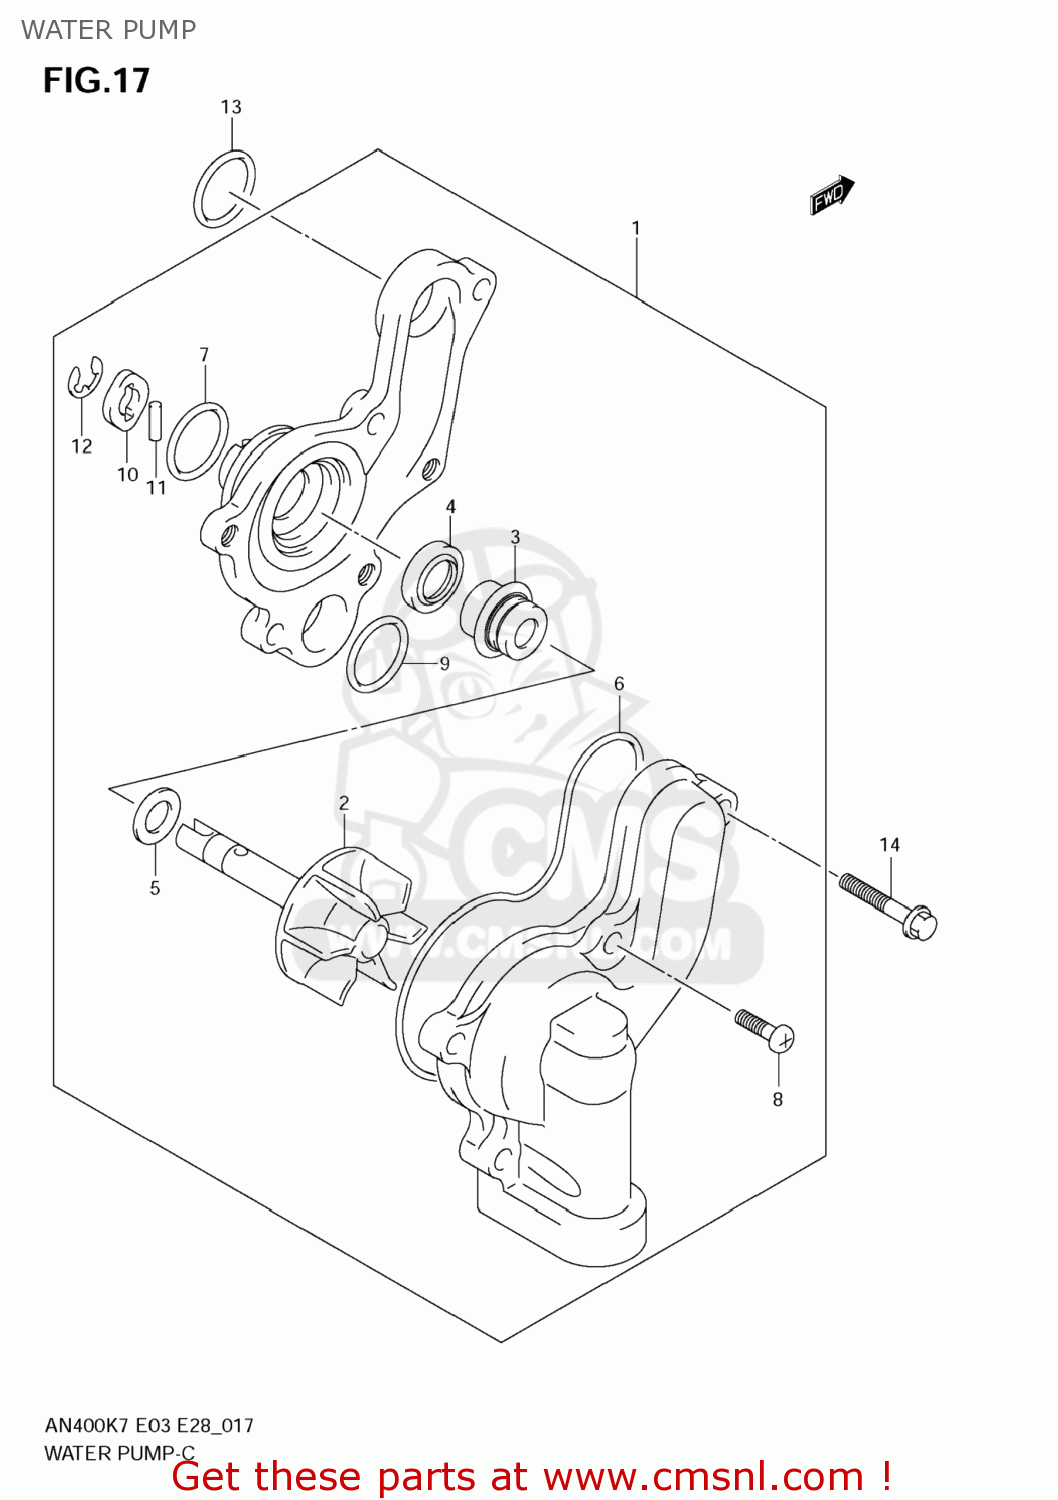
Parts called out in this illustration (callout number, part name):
1	PUMP ASSY,WATER
2	IMPELLER
3	SEAL,MECHANICAL
4	SEAL,OIL
5	WASHER
6	O RING
7	O RING,WATER PUMP HOLDER
8	SCREW
9	O RING(D:2.4,ID:21.8)
10	CAP
11	PIN
12	E RING
13	O RING(D:2.4,ID:21.8)
14	BOLT
